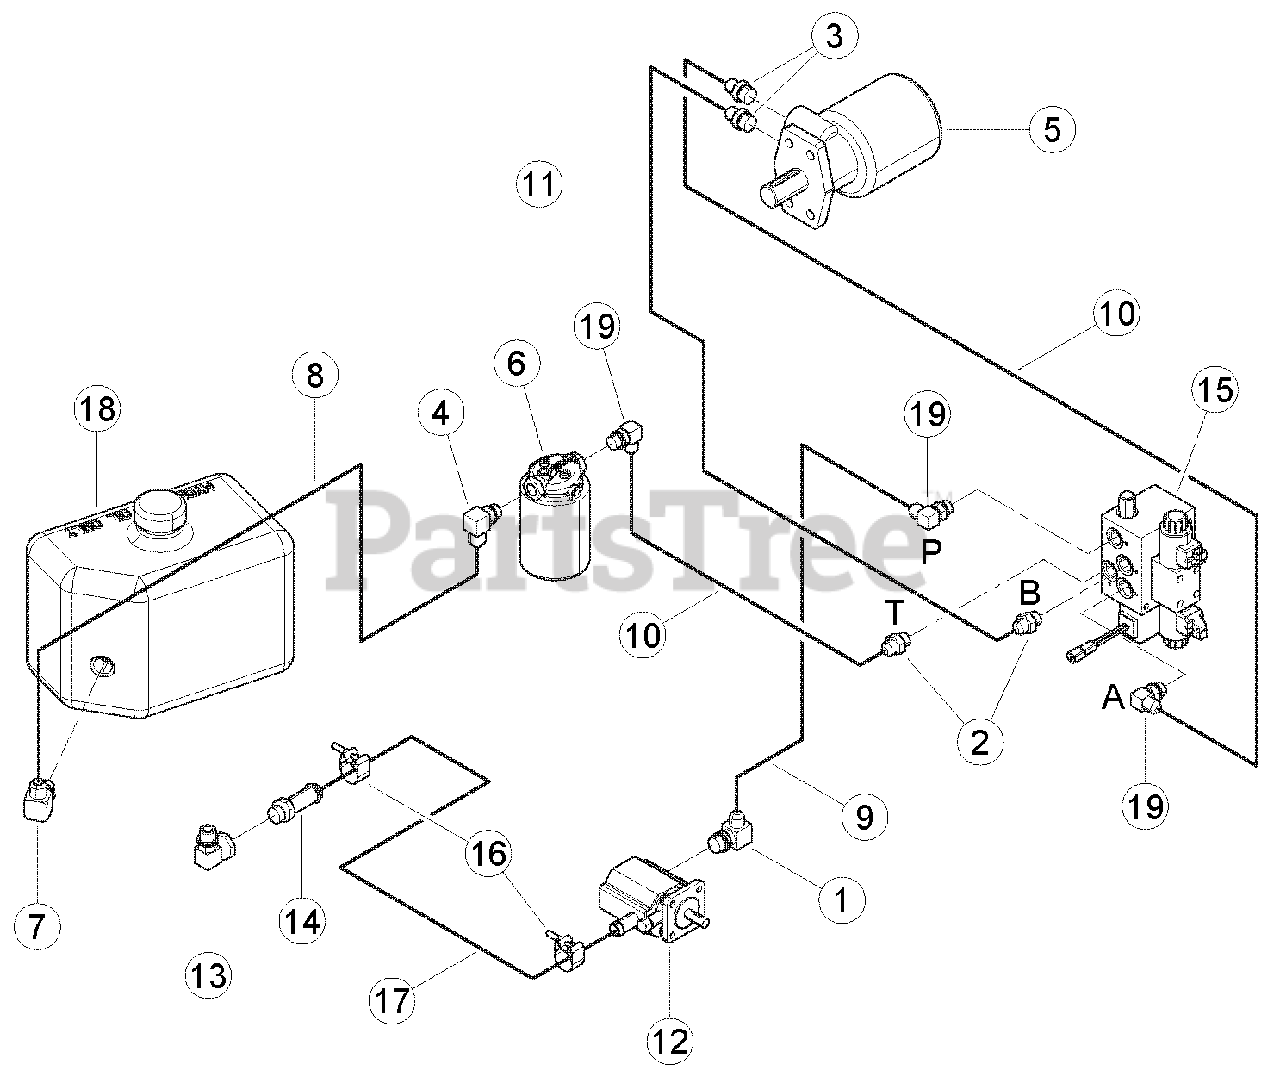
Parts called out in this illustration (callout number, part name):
1	ADAPTER, -10 MORING / -8 MJIC 90 DEG.
2	ADAPTER, -8 MORING / -8 MJIC
3	ADAPTER, -10 MORING / -8 MJIC
4	ADAPTER, -8 MORING / -10 MJIC 90 DEG.
5	MOTOR, 45 CU. IN. HYDRAULIC
6	FILTER, SPIN ON
7	ADAPTER, -10 MORING / -10 MJIC 90 DEG.
8	HOSE, .50 X 38 -10 FMJIC / -10 FMJIC
9	HOSE ASSY', -8 FMJIC / -8 FMJIC 90 X 21 IN.
10	HOSE ASSY', -8 FMJIC / -8 FMJIC 90 X 61 IN.
11	HOSE ASSY', -8 FMJIC / -8 FMJIC X 61
12	PUMP, CW HI/LO .605 DISP. (WAS 31323-00; REPLACED AND SUPERSEDED. FOR SERVICE ORDER PN 31671-00, PUMP)
12	PUMP, 2 STAGE CW HI/LO 0.605 DISP. (FOR SERVICE ORDER PN 75927-00, KIT, PUMP PB HIGH/LOW)
13	ADAPTER, -10 ORING X 3/4 PIPE 90 DEG (FOR SERVICE ORDER. PN 36017-00, ADAPTER, -10 MORING/.75 90 DEG. HOSE)
14	ADAPTER, 1 IN. HOSE BEAD X 3/4 PIPE (FOR SERVICE ORDER PN 36017-00, ADAPTER, -10 MORING/.75 90 DEG. HOSE)
15	ASSEMBLY, CHIPPER FLOW VALVE, 2-STAGE
16	CLAMP, 1" OD. HOSE T-BOLT
17	HOSE, 1 ID. X 22 IN. 100R4 HYD.
18	TANK, OIL RESERVOIR
19	ADAPTER, -8 MORING / -8 MJIC 90 DEG.
